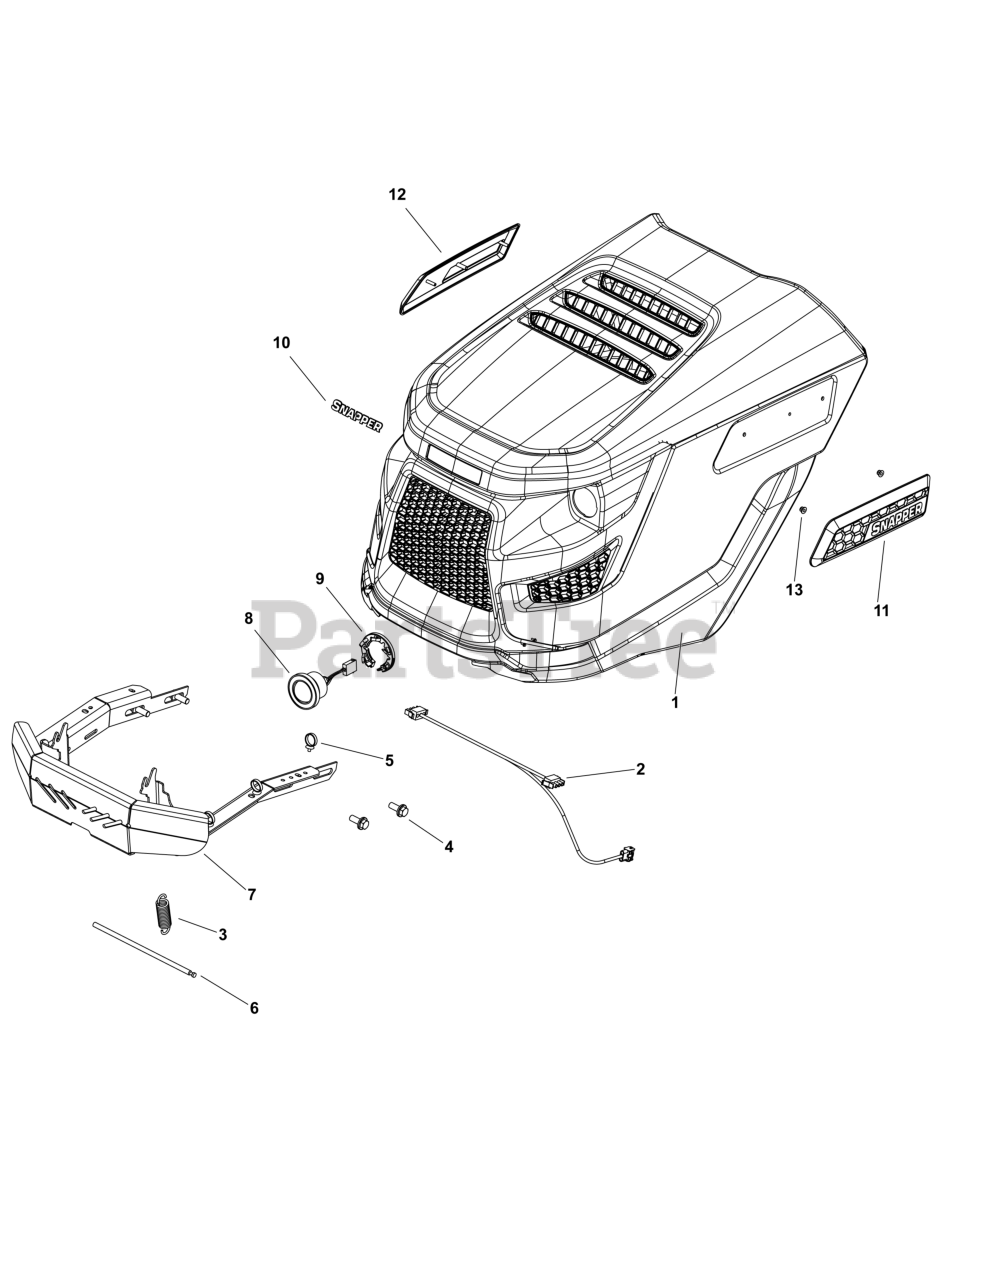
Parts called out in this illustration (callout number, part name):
2	CONNECTOR
10	DECAL, Brand
11	BADGE, Snapper, RH
12	BADGE, Snapper, RH
